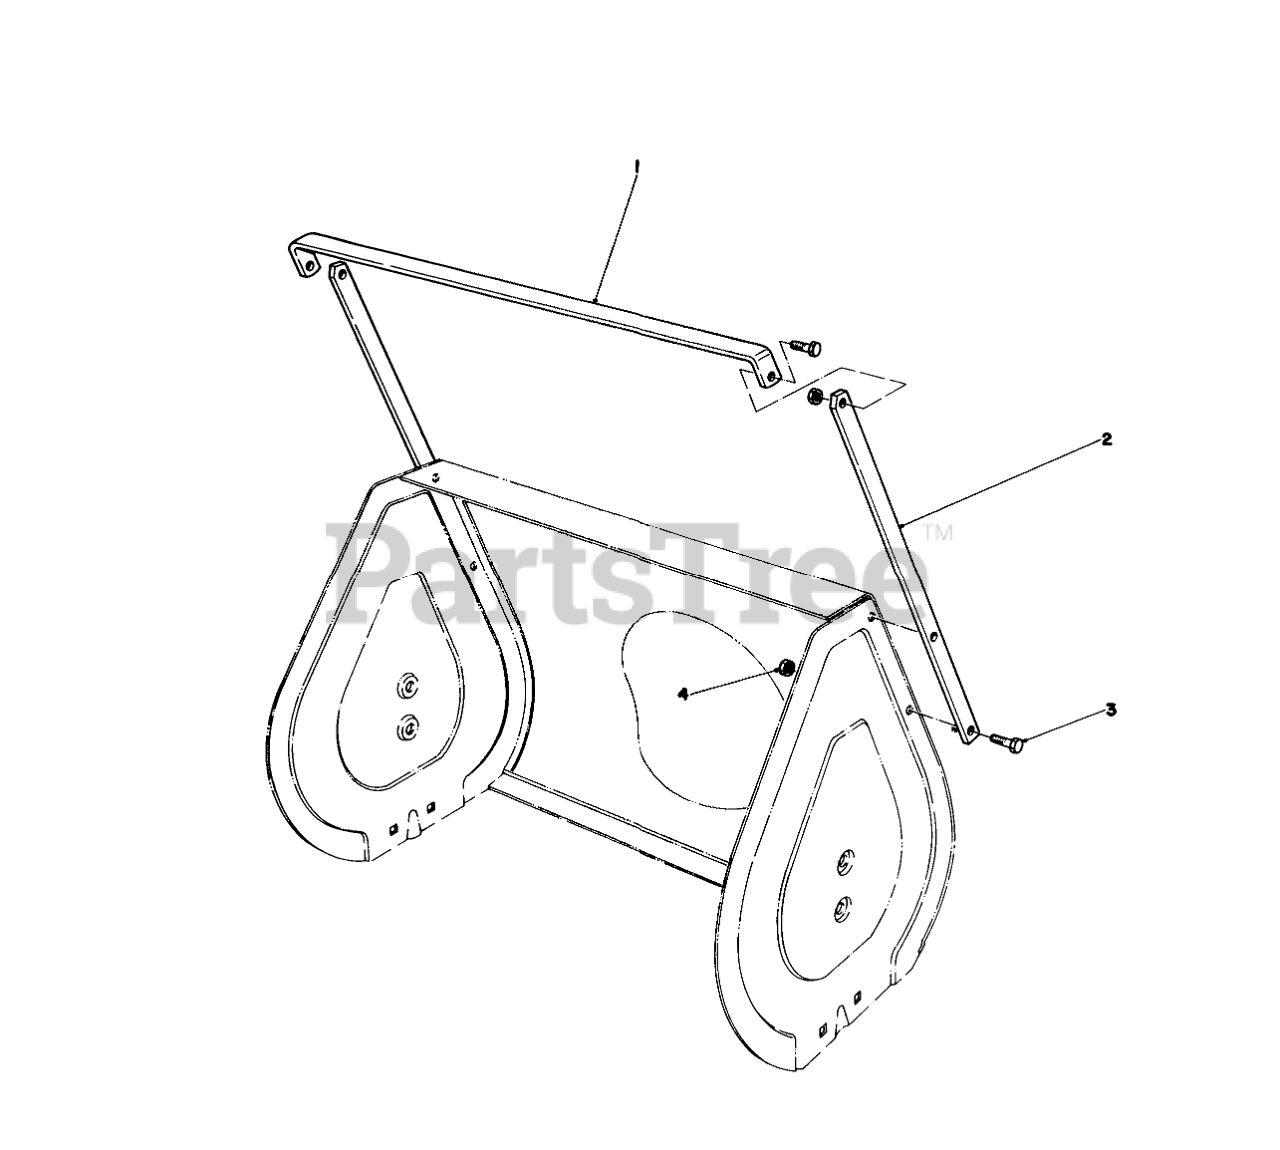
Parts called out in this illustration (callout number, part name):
1	Drift Breaker-Top
2	Drift Breaker-Side
3	SCREW-HH
4	NUT-LOCK, NI
